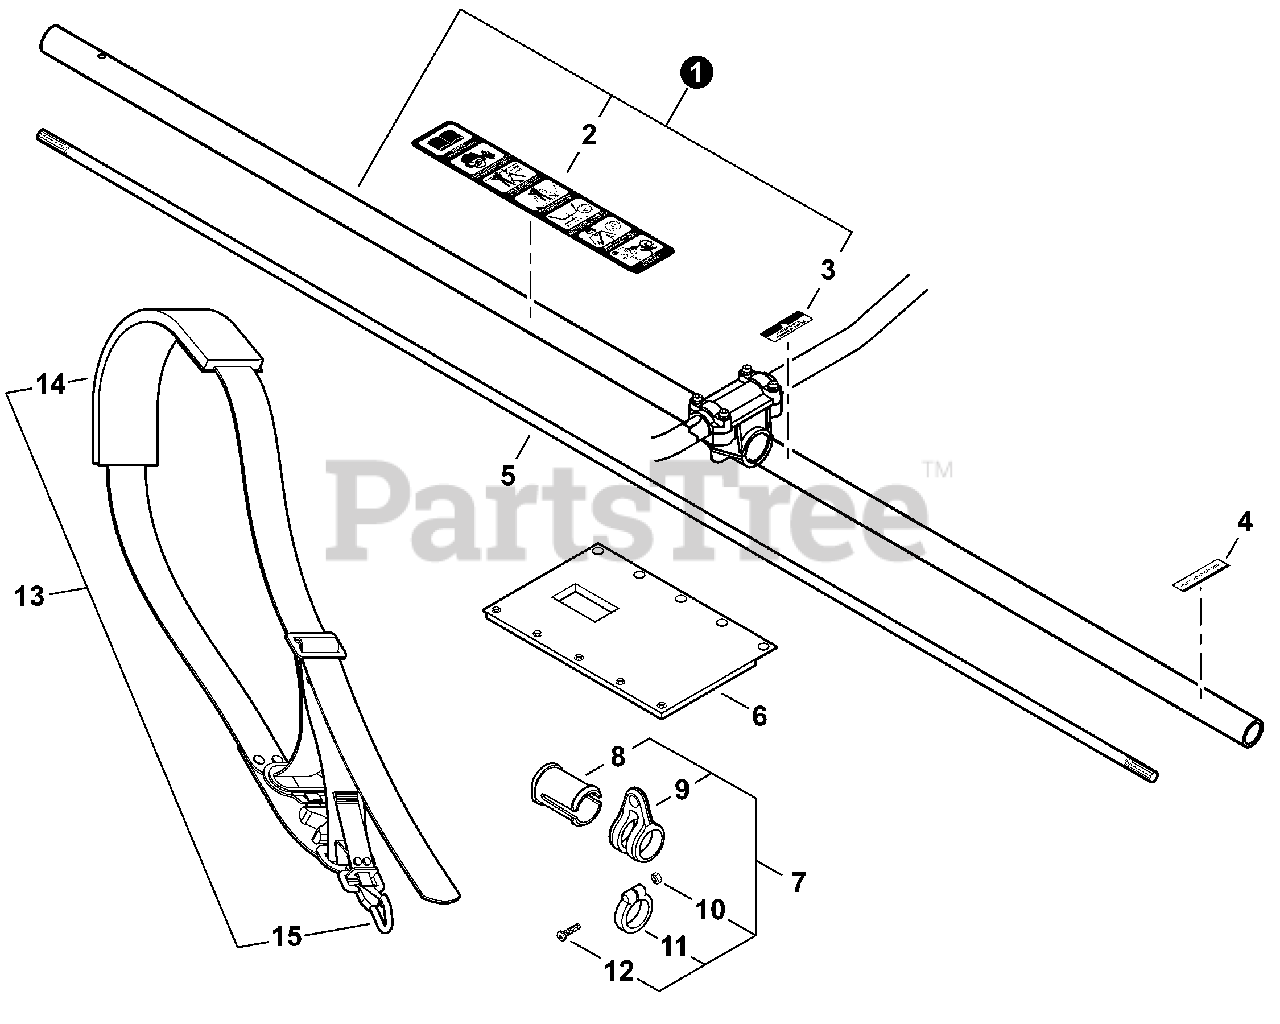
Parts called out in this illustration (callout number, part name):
1	MAIN PIPE ASSY
2	LABEL, CAUTION (BLADE CAPABLE)
3	LABEL, HANDLE
4	LABEL - ALIGNMENT
5	MAINSHAFT
6	CUSHION, MAIN PIPE
7	HANGER ASSY
8	COLLAR 24
12	SCREW M4×16
13	HARNESS ASSY, SHOULDER
14	PAD, SHOULDER
15	HOOK, SNAP
